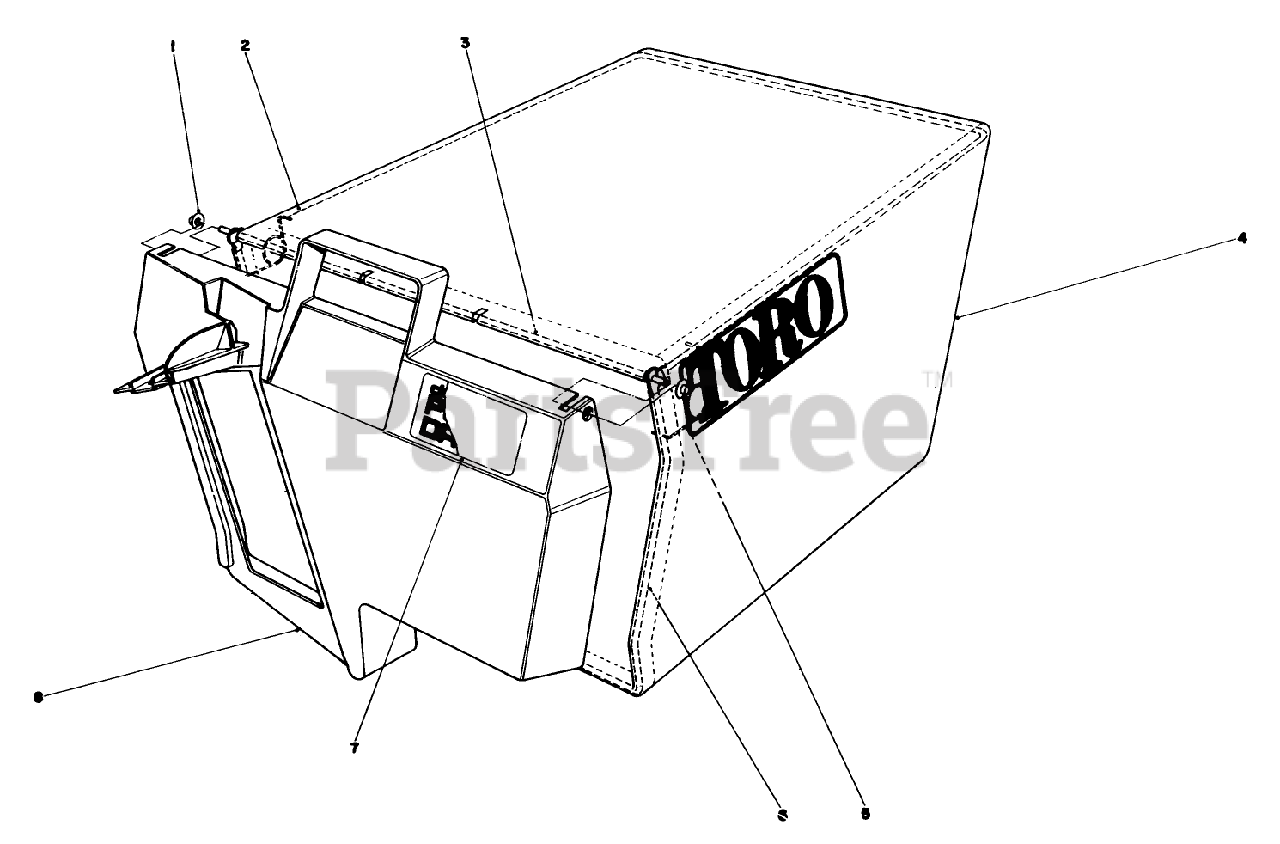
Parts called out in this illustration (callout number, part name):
1	NUT-PUSH
3	HINGE-DOOR, BAG
5	ADJ PLATE *B
6	FRAME-BAG
